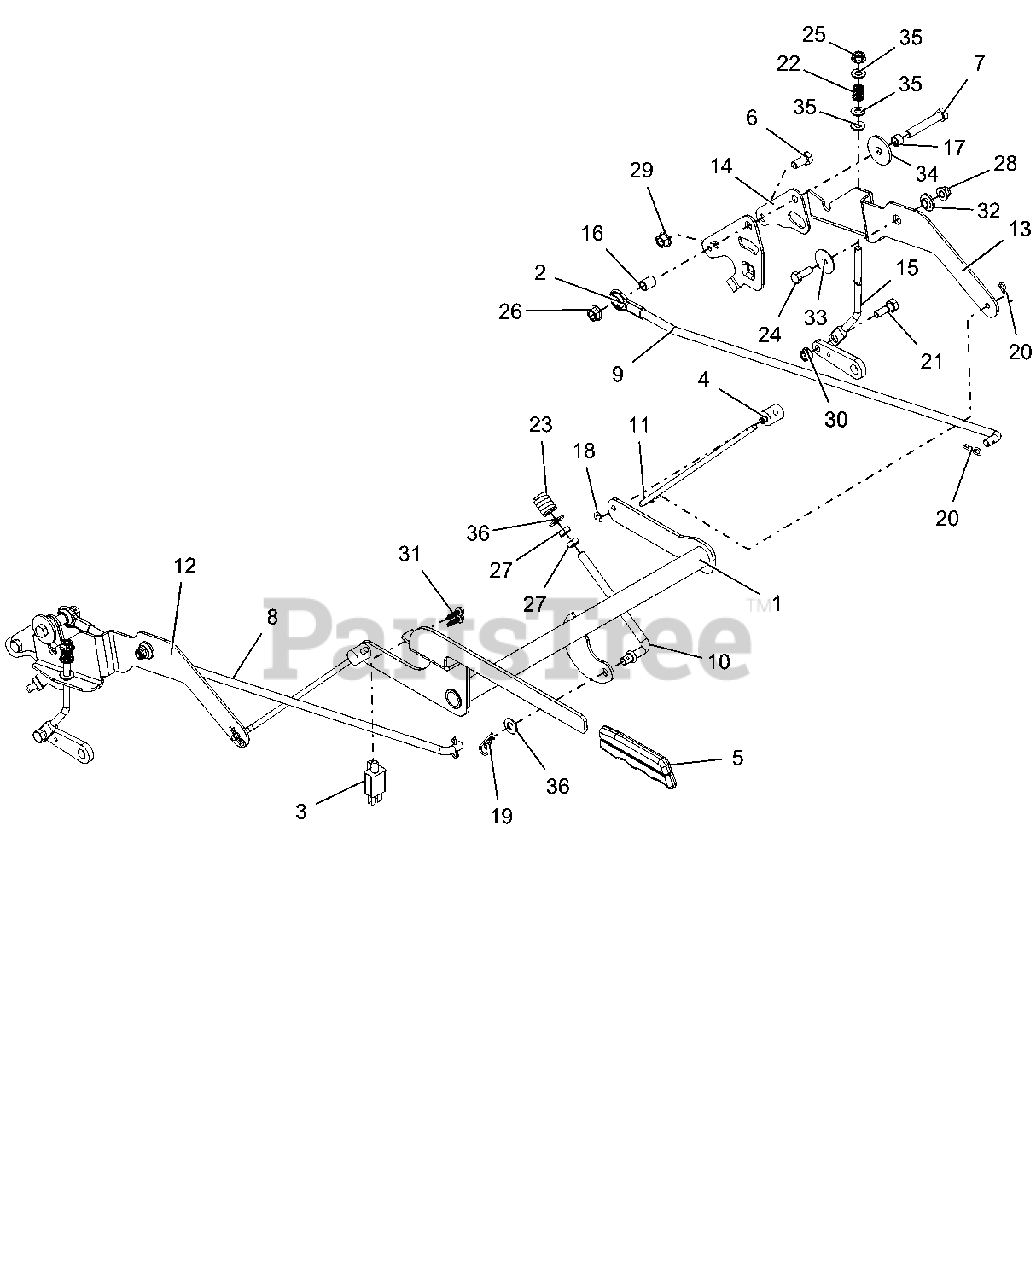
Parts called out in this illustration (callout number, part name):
1	WLDMT, BRAKE LEVER
2	ROD END, .38 RH
3	SWITCH- DOUBLE POLE N.O./N.O.
4	TRUNION, 1/4-20
5	GRIP, PARKING BRAKE (YELLOW)
6	BLT-HEX .38-16X.75 GR5 YWZC
7	BLT-HEX .38-16X2.25 GR5 YWZC
8	LINK, RH STEERING
9	ROD, STEERING LINKAGE LH
10	LINK, OVER CENTER BRAKE
11	LINK, BRAKE ARM
12	INTERLOCK, RH BRAKE LINK (BLACK)
13	INTERLOCK, LH BRAKE LINK (BLACK)
14	PLATE, TRANSAXLE ADAPTOR
15	LINK, BRAKE (XL)
16	SPCR, .385X.500X.652
17	SPCR, .385X.500X.350
18	RING, RETAINING-E .25X.025
19	PIN-COTR .09 X 1.50 YWZC
20	PIN, HAIR INT .08X.18X1.18 YWZC
21	BLT, SHLDR .38X.25 -.31-18X.75THD
22	SPRG, COMPRESSION
23	SPRG, COMPRESSION
24	BLT-HEX .31-18X.875 GR5 YWZC
25	NUT, LK-CTR-FLG .31-18 YWZC
26	NUT, LK-CTR-FLG .38-16 YWZC
27	NUT, JAM .375-16 YWZC
28	NUT-LK-NYL-FLG .31-18 YWZC
29	NUT, LK-TOP-FLG .38-16 YWZC
30	NUT, LK-TOP-FLG .312-18 YWZC
31	SCR-TAP #12X.75 BOSS INDHXHD
32	BSHG, FLG .325X.499X.26X.88
33	WSHR-FL-STL .347X1.254X.048 YWZC
34	WSHR-FL-STL .380X1.50X.125 YWZC
35	WSHR-FL-STL.344X.688X.065YWZC
36	WSHR-FL-STL.406X.812X.065 YWZ
